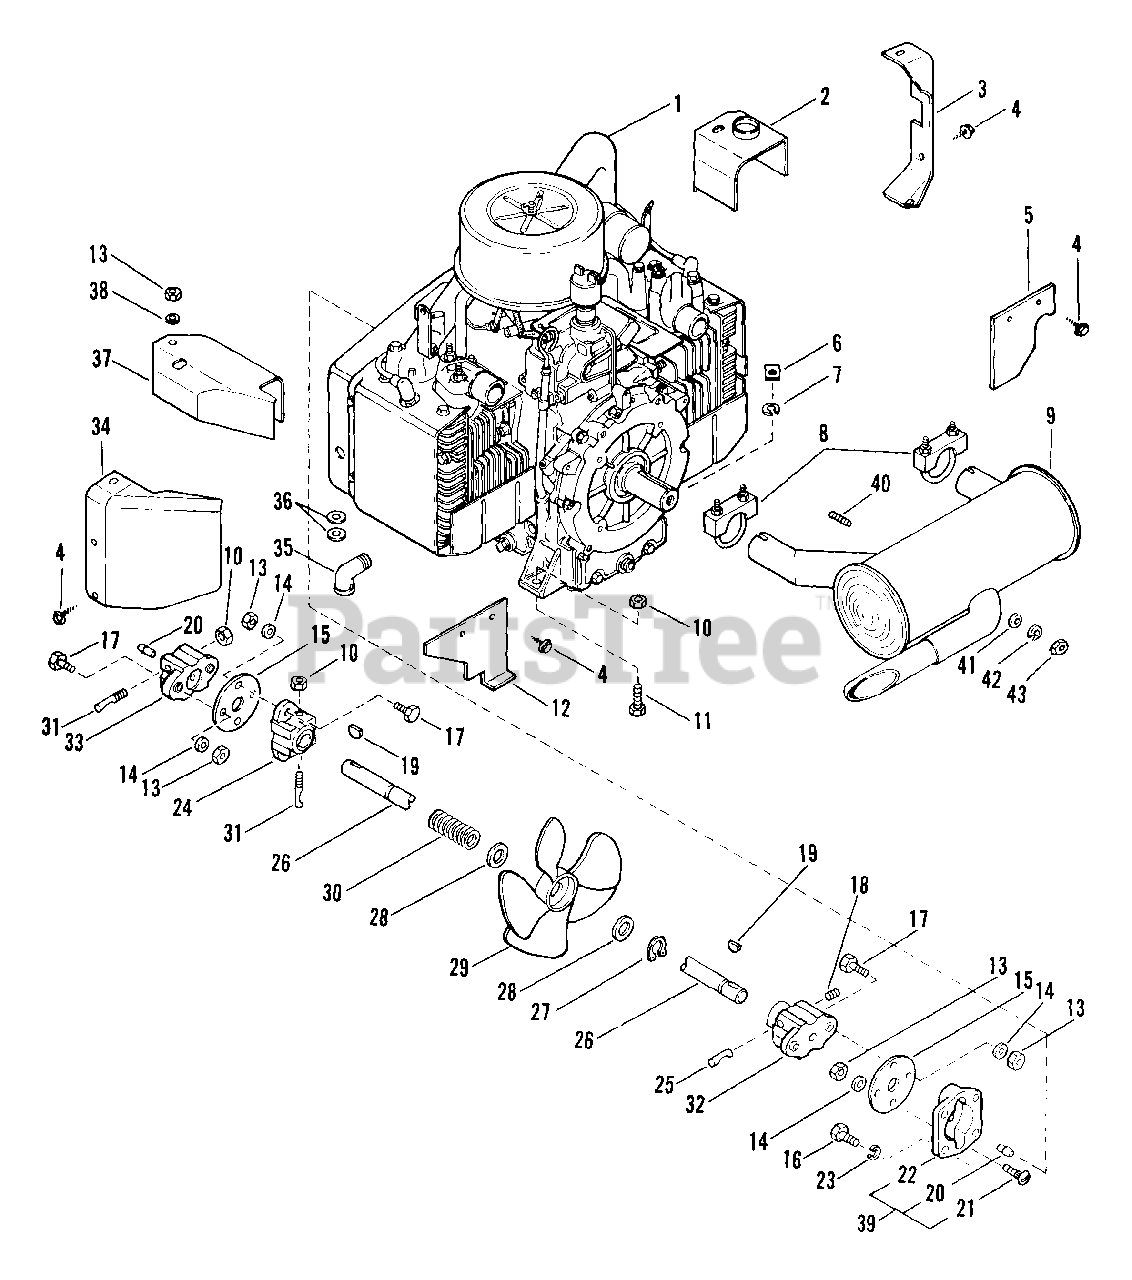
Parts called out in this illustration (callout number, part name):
1	Engine
1	17 H.&. KOHLER TWIN K422
1	19 HP KOHLER TWIN
1	KOHLER M18S #24513
1	KOHLER M20S #49533
2	LEFT EXHAUST SHIELD
3	LH CYLINDER BAFFLE
4	SCR-TAP 12-14X.62 HWH PL B
5	L.H. BAFFLE
6	NUT-SPECIAL-HDND .38-16 GR5 PL
7	WSHR-LK .375X.115 HVY PL
8	EXHAUST CLAMP - 1 1/2
9	MUFFLER-TWIN EXHAUST
10	NUT-LK TOP .375-16 GR C YWZC
11	BLT-HEX .38-16X1.25 PL GR5
12	R.H. BAFFLE
13	NUT-LK .312-18 GR A PL
14	WSHR-FL-STL.344X.688X.065PL
15	SPACER COUPLING
16	@BLT-HEX .38-16X.88 PL GR2
17	BLT-HEX .31-18X.88 PL GR2
18	SCR-SET .38-16X.50 SKHCUP OH
19	KEY-WDRF .188X.75X.313 SAE 9
20	PIN-GRV .313X.75 TP D
21	BLT-SERRDHD SL .31-18X.87 PL
22	DRIVE HUB - FLYWHEEL TWIN
23	WSHR-LK .375X.094 MED PL
24	DRIVE HUB
25	LOCK STUD
26	DRIVE SHAFT
27	RG-RTNG-EXT .750X.042
28	WSHR-HDND-THRST .758X1.23X.031
30	SG-COMP .120X.75X2.50 WLD48
31	LOCK STUD
32	DRIVE HUB- TWIN SHAFT
32	DRIVE HUB - TWIN SHAFT
33	DRIVE HUB - HYDRO
34	RH CYLINDER BAFFLE
34	R H CYLINDER BAFFLE
35	STREET ELBOW
36	WSHR-FL-STL .38X.875X.083 PL
37	RIGHT EXHAUST SHIELD
38	WSHR-FL-STL .323X.625X.062 PL
39	ENGINE COUPLING ASSEMBLY - TWI
40	ENGINE STUD
41	WSHR-FL-STL .250X.562X.049 PL
42	WSHR-LK .250X.077 HVY PL
43	NUT-HEX .250-20 PL
